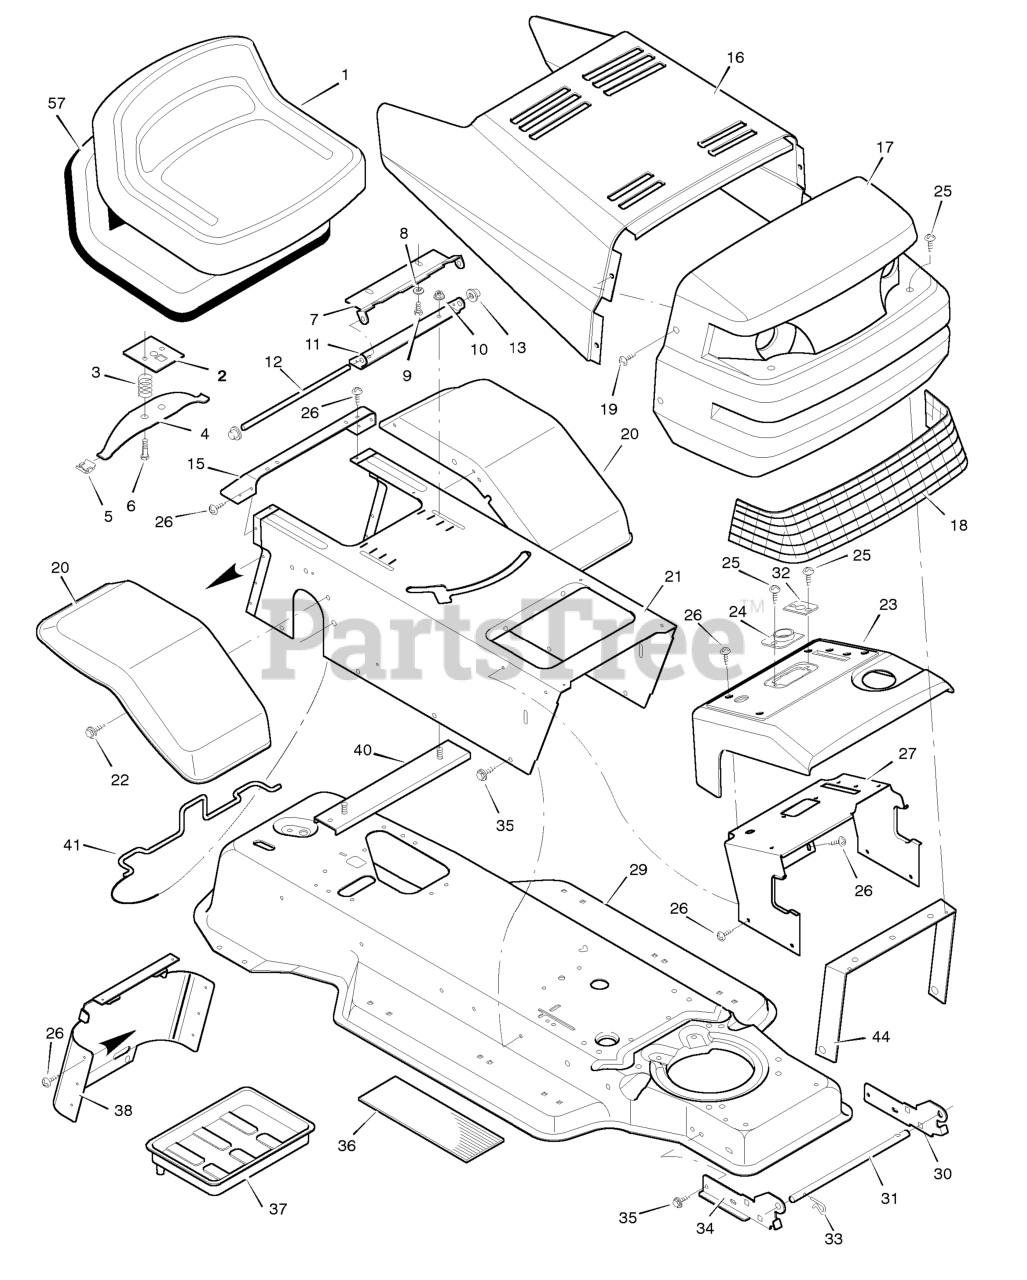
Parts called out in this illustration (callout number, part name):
2	Plate Assembly, Switch
3	Spring, Compression
4	Spring, Seat
5	Glide, Spring
6	Bolt, Shoulder
7	Support, Seat
8	Lockwasher
9	Bolt, Hex
10	Locknut, Flange
11	Bracket, Pivot
12	Rod, Pivot
13	Cap, Push On
15	Fender, Apron
17	Grille Assembly
21	Console Assembly
23	Dash Panel
24	Bearing, Steering
26	Screw
27	Support, Dash
29	Frame Assembly
30	Bracket, Left Grille
31	Rod, Pivot
32	Bearing
33	Pin, Hair
34	Bracket, Right Grille
37	Tray, Battery
38	Cap, Console
39	Bolt
40	Channel Assembly
41	Clamp, Battery
44	Brace, Grille
57	Pan, Seat (with foam)
